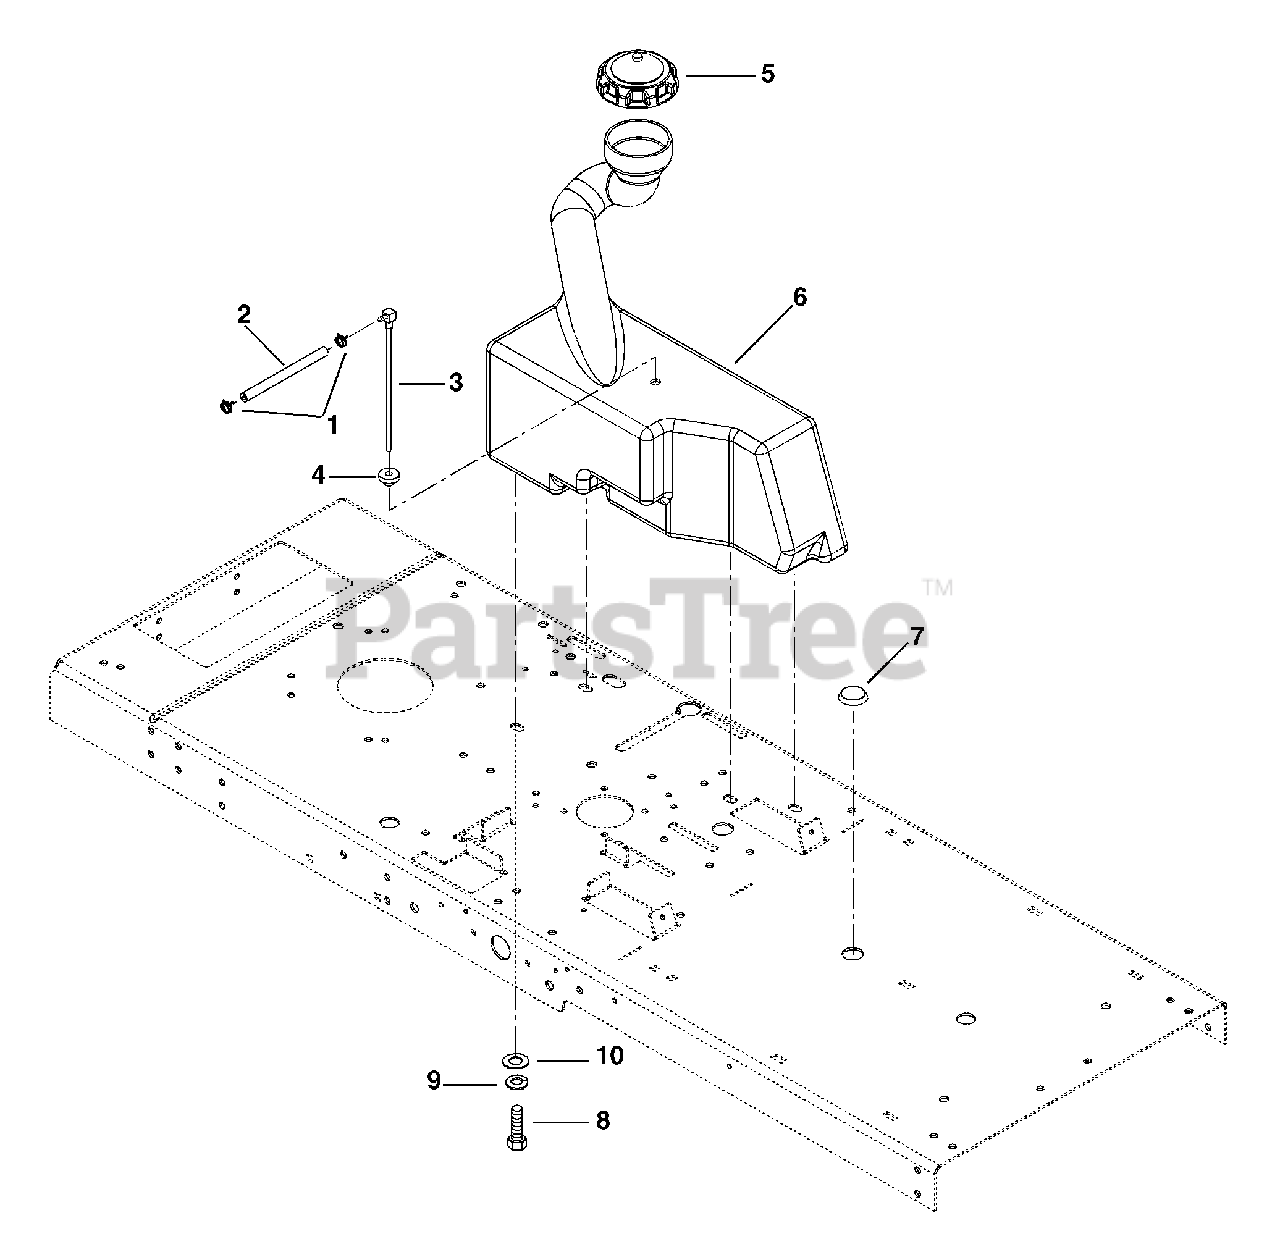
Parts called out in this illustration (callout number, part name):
1	Clamp-Hose Wire
2	Hose-Fuel .25 I.D. x 22" Long
2	Hose-Fuel .25 I.D. x 17.5" Long
3	Fitting-Tank
4	Bushing
5	Cap-Fuel
6	Fuel Tank
7	Plug-Button
8	Bolt-Hex .312-18 x .75 Grade 5
9	Washer-Lock
10	Washer-Flat-Steel .38 x .875 x .083
